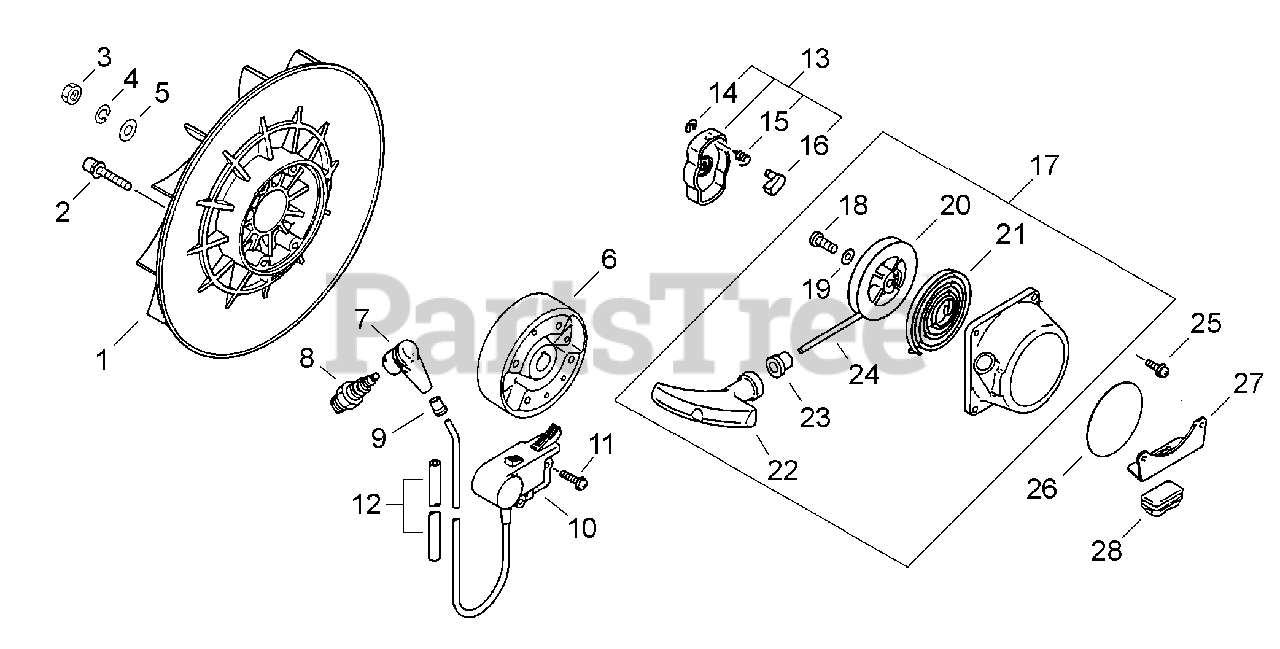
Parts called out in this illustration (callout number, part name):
2	BOLT - 5X35
3	NUT - 10
4	LOCKWASHER - 10
5	WASHER - 10
6	FLYWHEEL
7	CAP, SPARK PLUG
8	SPARK PLUG -- BPMR-7A
9	ADAPTER, SPARK PLUG CAP
10	COIL, IGNITION
11	SCREW - 5X18
13	STARTER PAWL ASSY
14	RING, RETAINING - 4
15	SPRING, RETURN
16	PAWL, STARTER
17	STARTER ASSY
19	WASHER
20	REEL, ROPE
21	SPRING, REWIND
22	GRIP, STARTER
23	GUIDE, ROPE
24	ROPE, STARTER - 4X1110
25	SCREW - 4X18
26	LABEL - ECHO
